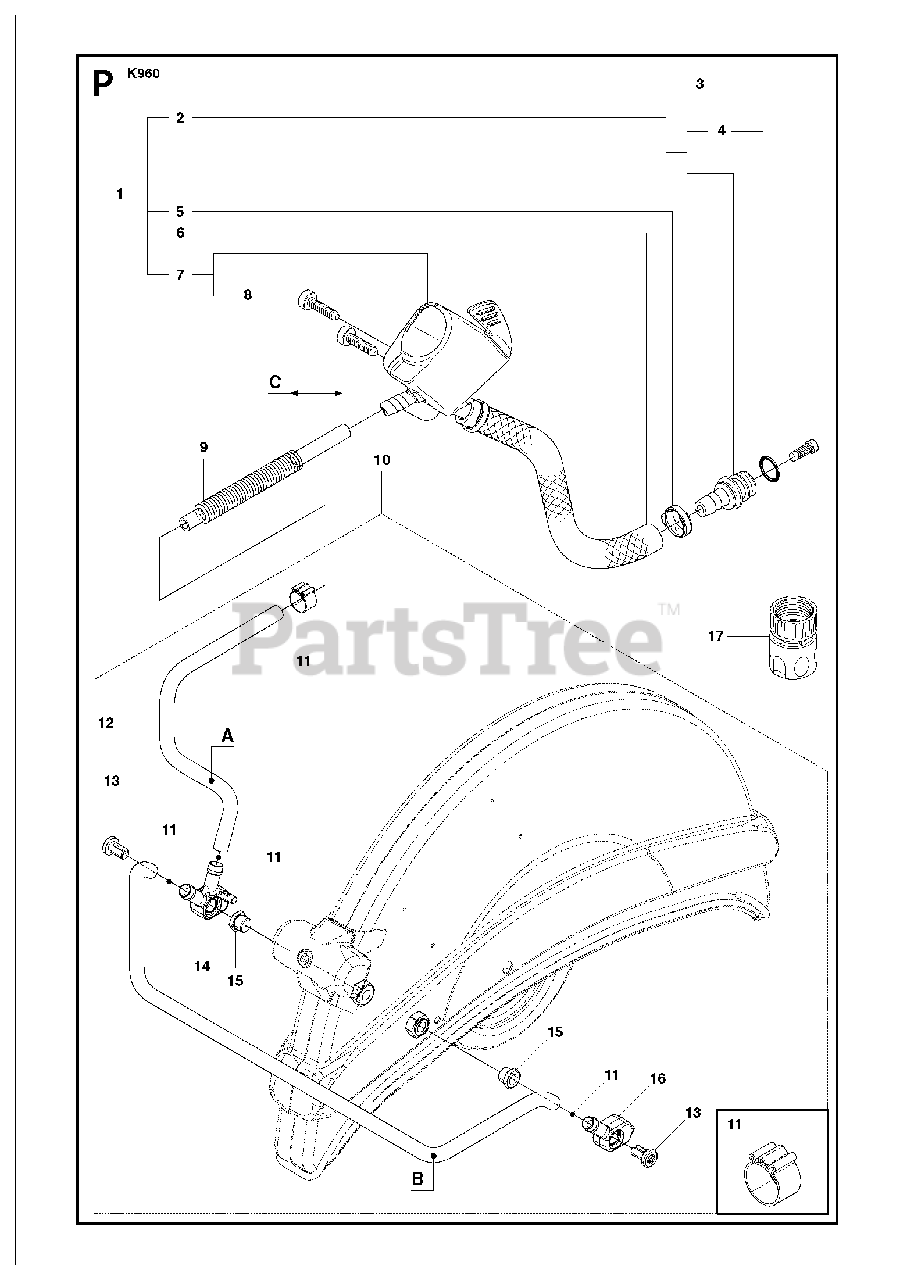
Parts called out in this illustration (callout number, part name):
1	HOSE KIT2, 5-7
2	NIPPLEIncl. 3, 4
5	HOSE CLAMP
8	SCREW ITXSCT
9	PROTECTIVE SPRING
12	HOSE620 mm
13	SCREW ITXSCM
